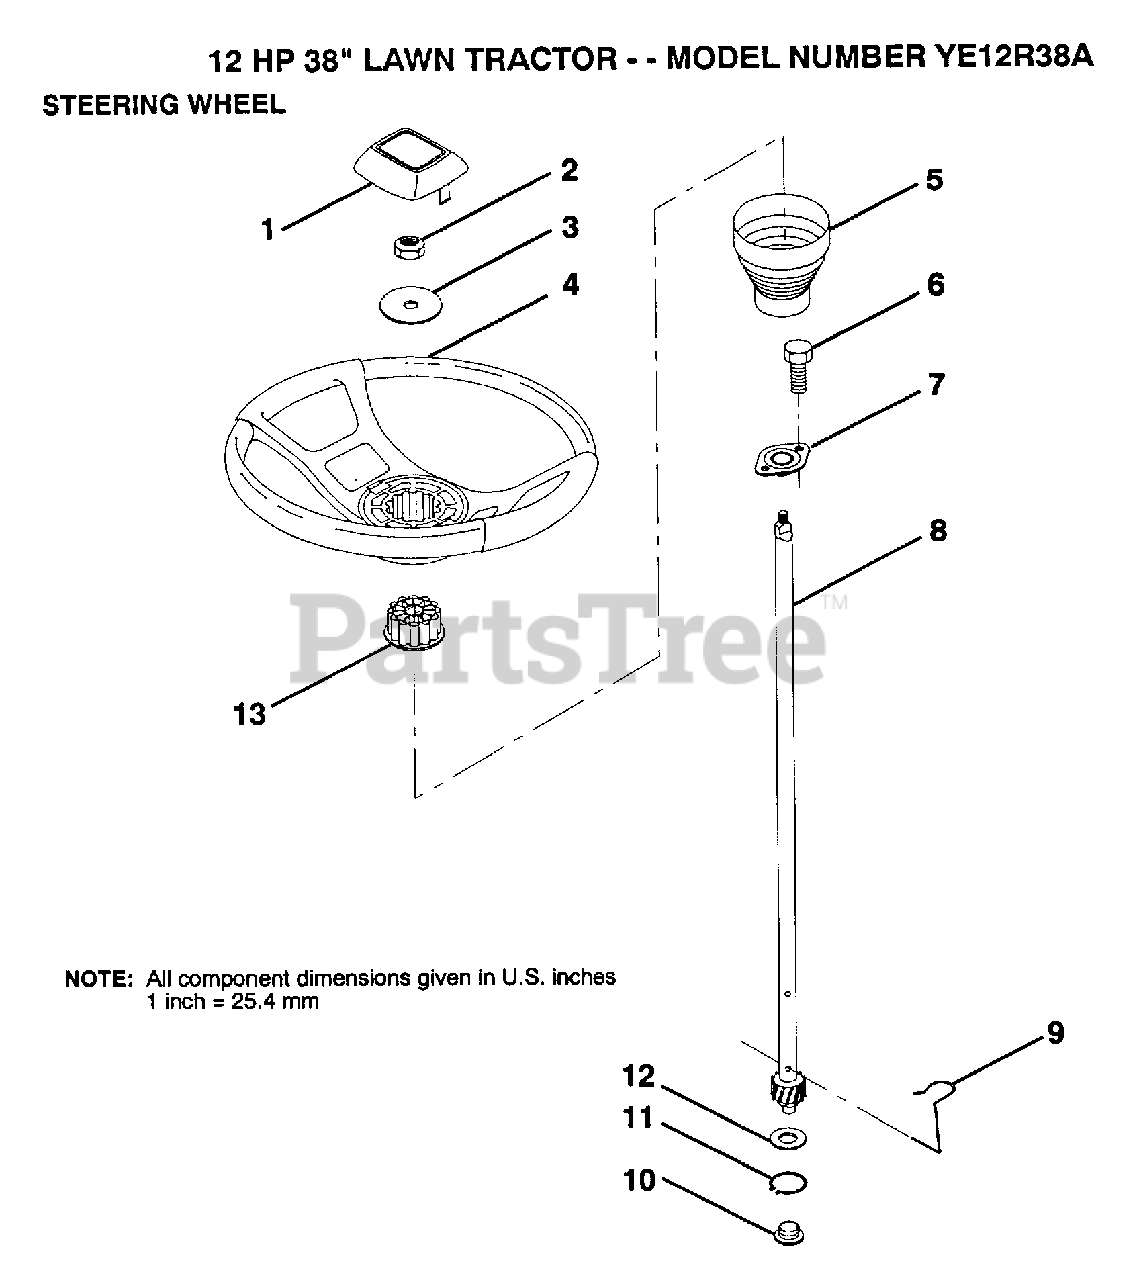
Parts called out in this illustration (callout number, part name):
1	INSERT STEERING
2	GRIPCO NUT
3	WASHER T
9	STEERING CLIP
10	BUSHING STEER LWR
11	RING
12	WASHER LT
13	ADAPTER-WHEEL LT
